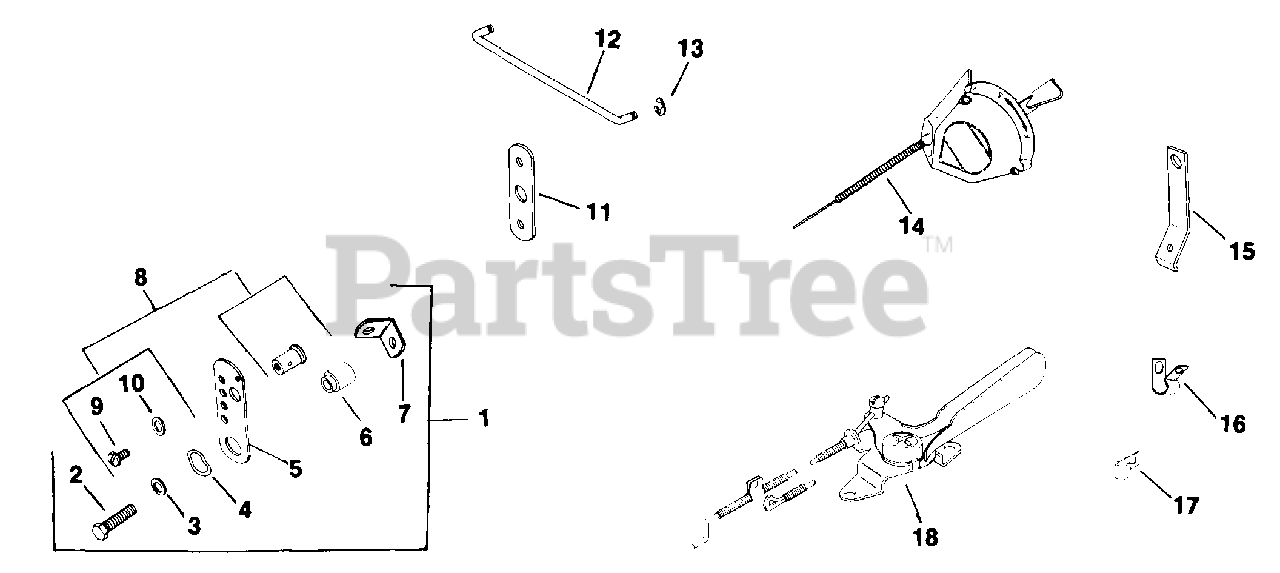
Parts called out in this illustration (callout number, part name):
3	WASHER, FLAT 1/4" (O.D. 1/2")
4	WASHER, SPRING 11/32"
5	BRACKET
7	BRACKET, ADJUSTING SCREW - DISCONTINUED
8	KIT, CLAMP
9	SCREW - USE 41 086 20
10	WASHER, FLAT 1/4"
11	LEVER, BELLCRANK
13	RETAINER
